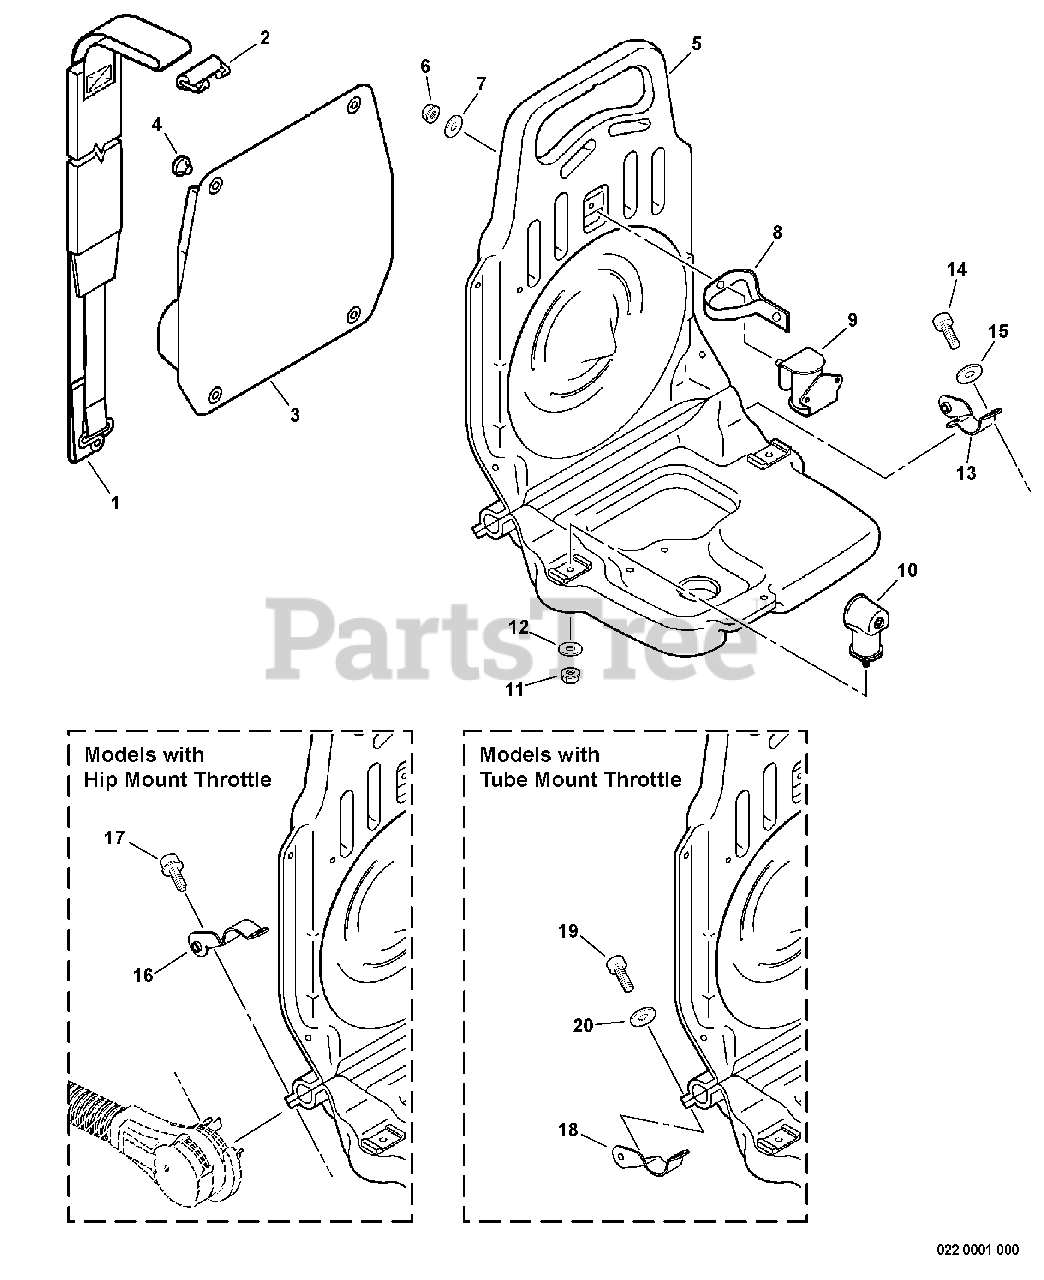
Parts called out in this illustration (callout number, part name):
1	HARNESS ASSY, BACKPACK
2	CLIP, HARNESS
3	CUSHION, BACKPACK
5	FRAME, BACKPACK
6	NUT, FLANGE M5
7	WASHER 5.5×16×2T
8	RETAINER
10	CUSHION, FRAME 5
11	NUT, FLANGE M5
12	WASHER 5.5×16×2T
13	CONNECTOR, HARNESS (B)
14	BOLT 5×20
15	WASHER 5.5×16×2T
16	BRACKET, HARNESS
17	BOLT, TAPPING 5×25
18	CONNECTOR, HARNESS (A)
19	BOLT 5×20
20	WASHER 5.5×16×2T
